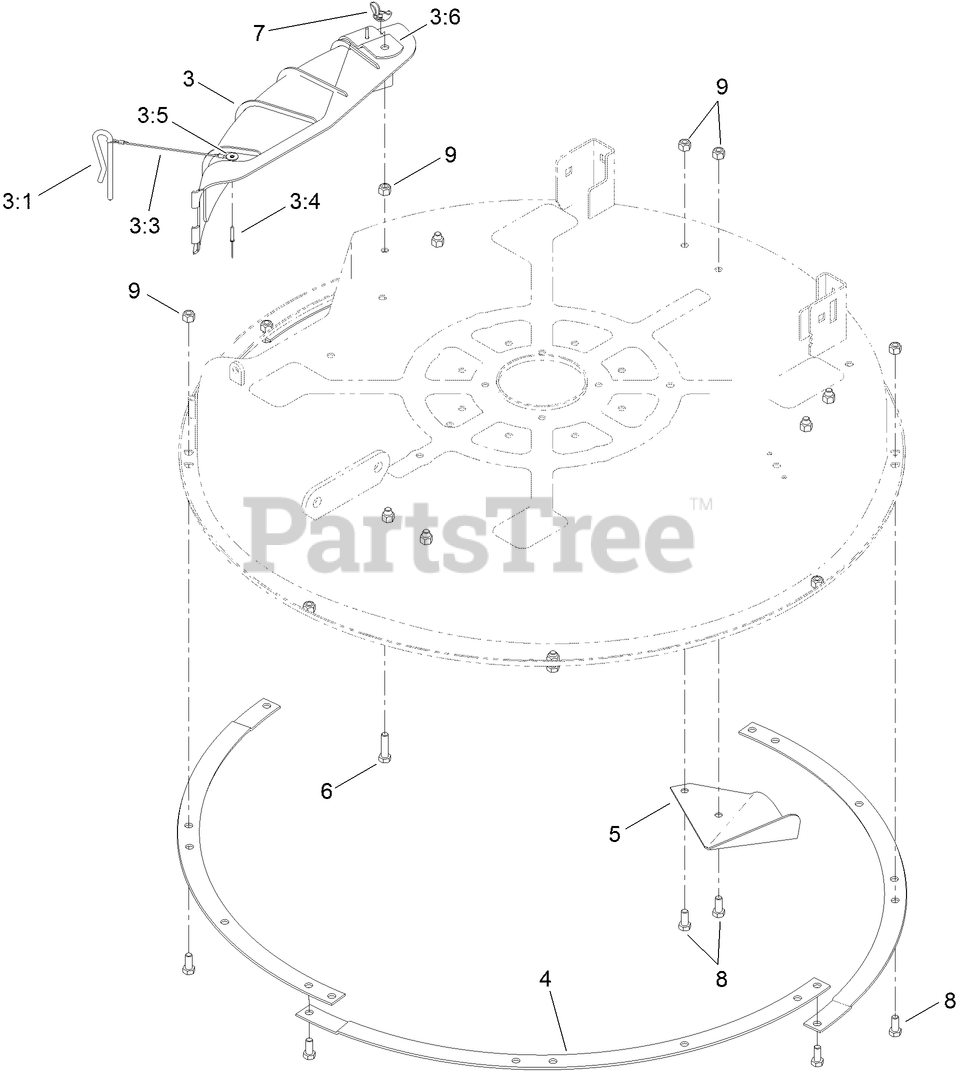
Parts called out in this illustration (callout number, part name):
3	DISCHARGE COVER ASM
3:1	PIN-LOCKING, CHUTE
3:3	LANYARD
3:4	RIVET-BLIND
3:5	WASHER-PLAIN
4	RING-DECK
6	SCREW-HH
7	NUT-WING
8	SCREW-HH
9	NUT-LOCK, NI
